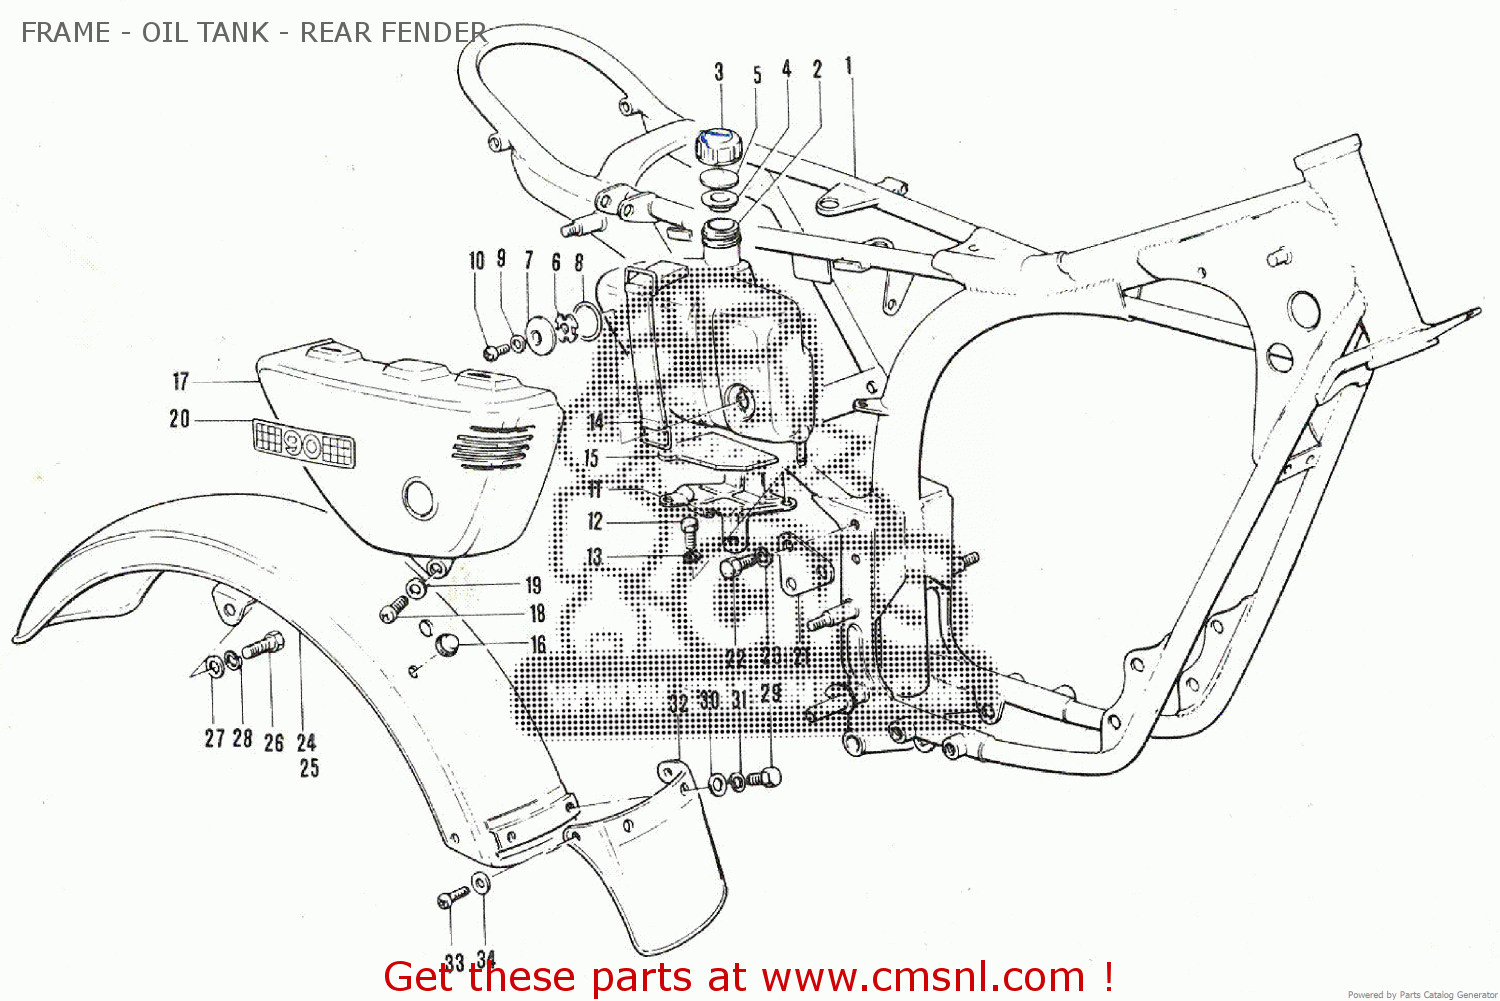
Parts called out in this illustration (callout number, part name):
1	FRAME
2	OIL TANK
3	CAP,OIL TANK
4	GASKET,OIL TANK CAP
5	OIL TANK CAP GASKET (B)
6	OIL INSPECTION PLATE
7	LENS,INSPECTION
8	O RING(D:3,ID:23)
9	GASKET(5X9.5X1) (NAS)
10	SCREW
11	OIL TANK HOLDER
12	BOLT
13	LOCK WASHER
14	BAND
15	CUSHION
16	CUSHION
17	COVER,FRAME,RIGHT
18	CROSS HEAD SCREW
19	WASHER(6.5X16X1.2)
20	RH COVER EMBLEM
21	PLATE,ENGINE MOUNTING
22	BOLT
23	LOCK WASHER
25	FENDER,REAR
26	BOLT
27	WASHER
28	LOCK WASHER
29	BOLT
30	WASHER
31	LOCK WASHER
32	MUD GUARD,REAR FENDER
33	SCREW
